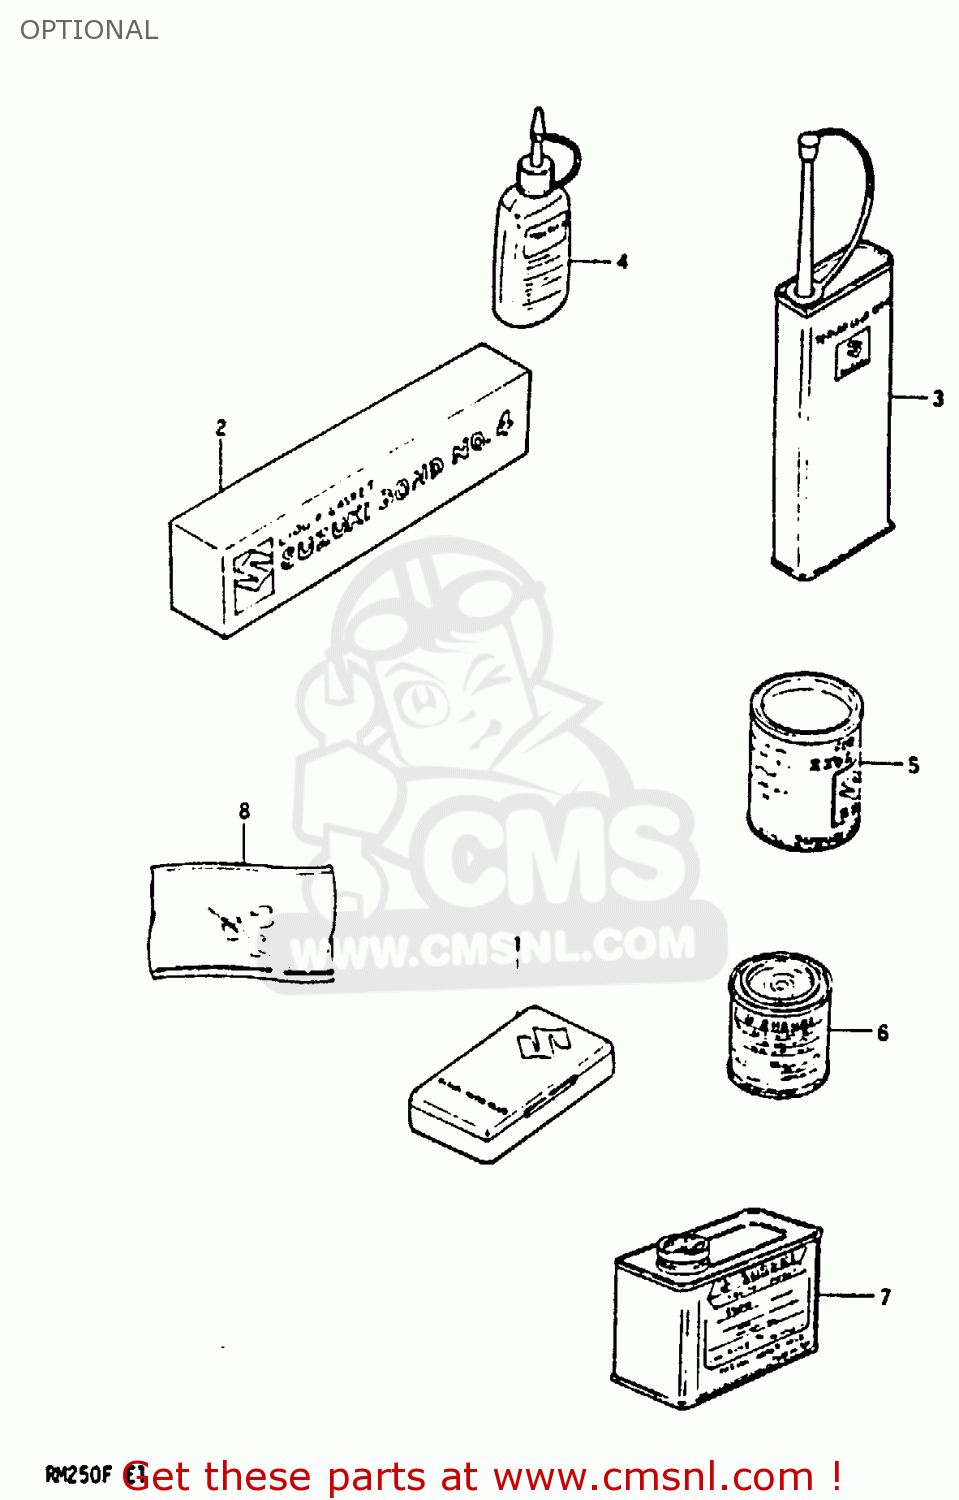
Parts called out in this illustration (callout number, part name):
1	TUBE REPARING TOOL
2	BOND 1104
3	THREAD LOCK NO.1401 CLEAR 200G
4	THREAD LOCK NO
5	GREASE(C)EP2 LITHIUM 150G
6	PAINT (MEDIUM GOLD)
7	PAINT (MEDIUM GOLD)
8	ANTI-LEAK ADDITIVE
